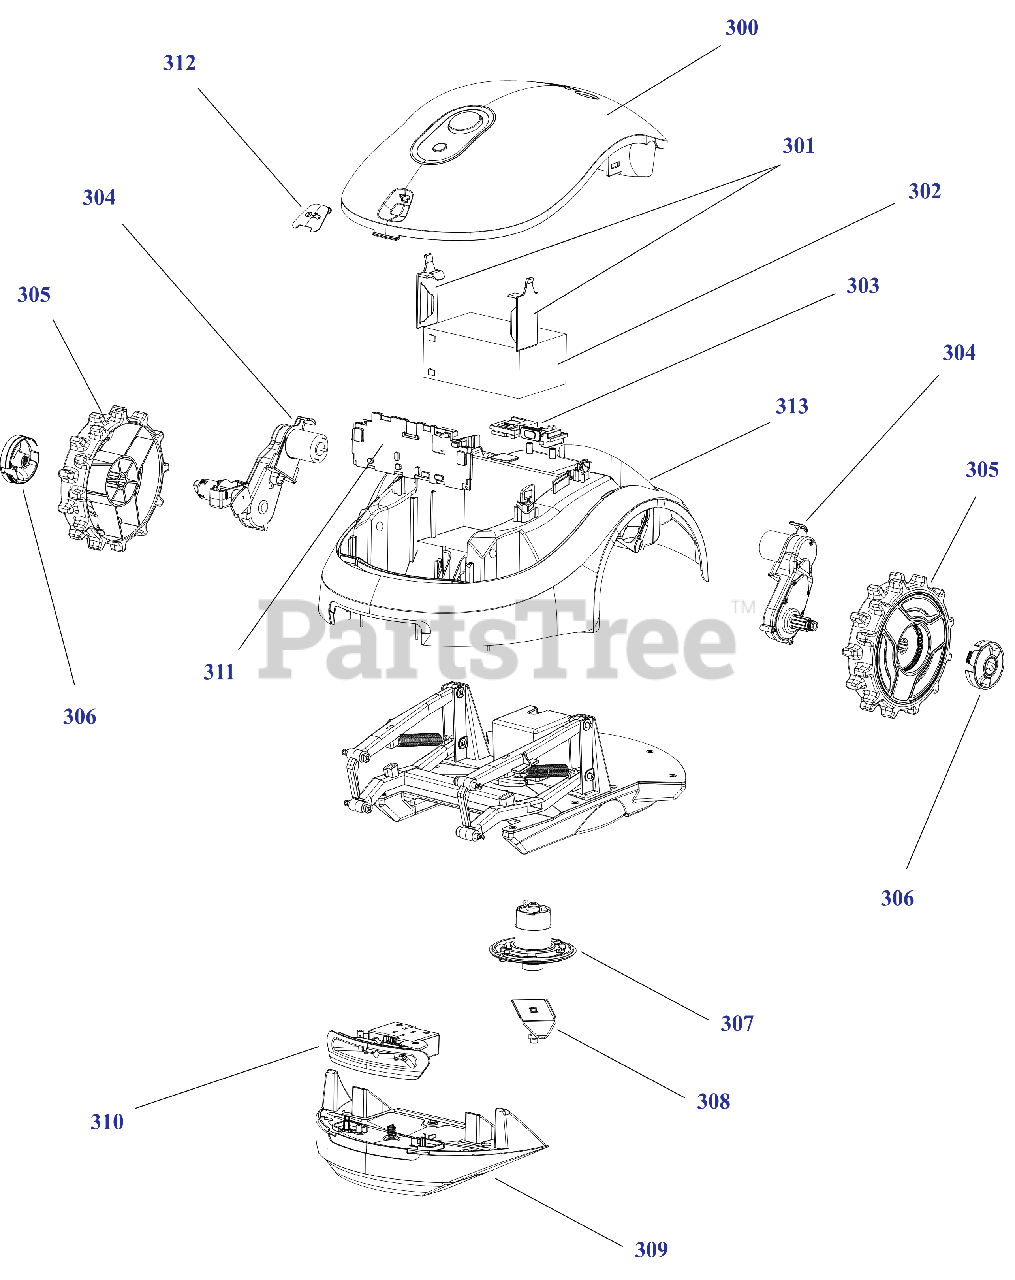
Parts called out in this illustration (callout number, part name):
300	COVER ASSY (GRN)AND DISABLING RX
301	BATTERY LOCKERS RX
302	BATTERY (RX)
304	DRIVE MOTOR RX
306	WHEEL LOCK CAPS RX
307	MOWING MOTOR RX
309	SKI ASSEMBLY RX
310	NOZZLE ASSEMBLY RX
311	MAIN BOARD RX
312	DISABLING DEVICE FOR RX
313	CHASSIS ASSEMBLY RX
314	10MM POWER SUPPLY WALL MT 17V
316	BASE STATION HEAD ASSEMBLY RX
317	BASE STATION RX
318	MOWING MOTOR CABLE
320	MAWING DECK ASSEMBLY RX
321	MOWING DECK SPRIN RX
322	MOWING ARM LONG PIN RX
323	MOWING ARM SHORT PIN RX
324	SCREW K4X20 WN 1451-ZP TOREX
325	EJOT K30X35 WN-1451 TORX
